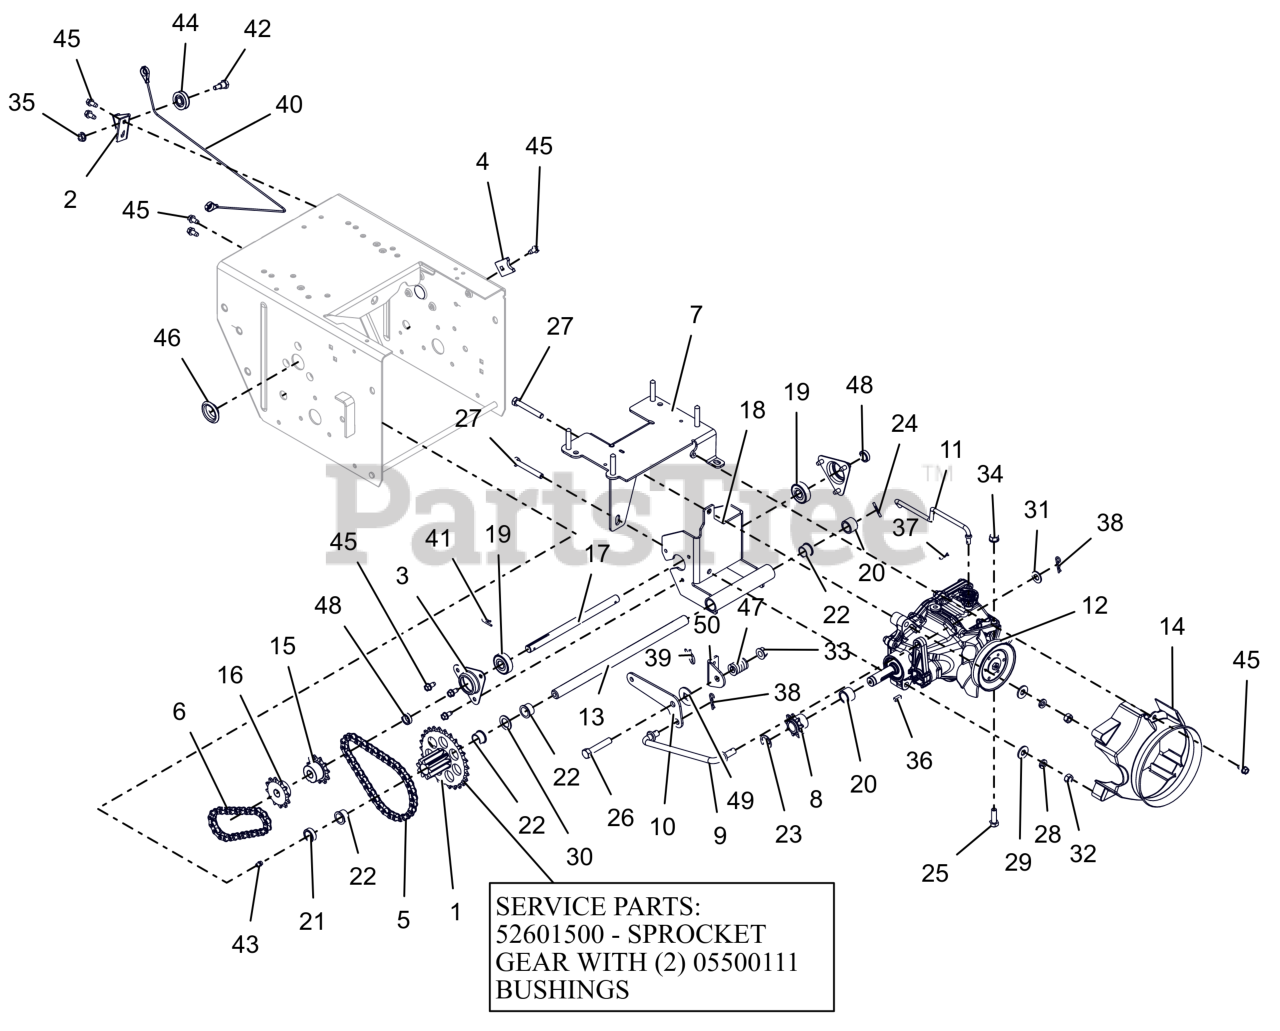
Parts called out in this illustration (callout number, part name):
1	PINION & SPROCKET
1	PINION & SPROCKET W/BUSHINGS
2	BRACKET, CABLE PULLEY
3	FLANGE, BEARING
4	TAB, ANTI ROTATION
5	ROLLER CHAIN #41 - 34 PITCHES
6	CHAIN-ROLLER #41X26 PITCHES
7	BRACKET, HYDROSTATIC TRANS XLG
8	SPROCKET, PINION 9T W/KEY
9	ROD, HYDRO TRANS SHIFT
10	PIVOT, HYDRO TRANS SHIFT
11	ROD, HYDRO BYPASS
12	TRANSMISSION, HYDROSTATIC
13	SHAFT, PINION - HARDENED
14	SHROUD, HYDROGEAR RT-310
15	SPROCKET, 11 TOOTH
16	SPROCKET, 12 TOOTH
17	SHAFT, REDUCTION HEAT TREATED
18	SUPPORT, REDUCTION-BWT
19	BRG-BALL .500X1.38X.437
20	SPACER, .635X.880X.611
21	BSHG-SLV, .635X.880X.305
22	BSHG-FLG .625X.750X.500X.875
23	RG-RTNG-EXT .625X.042
24	@PIN-GRV .125X1.00 TP E ALLOY
25	BLT,HEX .31-18X1.00 G5 ZCC
26	BLT,HEX .38-16X2.00 G5 ZCC
27	BLT, HEX .31-18X2.25 G5 ZCC
28	WSHR, LK-HVY .312X.097 ZCC
29	WSHR,FLT .375X.875X.083 ZCC
30	WSHR, FLT .630X1.005X.062 ZCC
31	WSHR,FLT .406X.812X.065 ZCC
32	NUT, HEX .312-18 ZCC
33	NUT-LK-TOP-FLG .38-16 ZC120
34	NUT-LK-TOP-FLG .312-18 GF ZCC
35	NUT-LK-TOP-FLG .250-20 GF ZCC
36	KEY-SQ .187 X .50 X .187
37	PIN, HAIR #178 .06X.77 ZCC
38	PIN, HAIR #213 .08X1.19 ZCC
39	PIN, SPRING CLIP
40	CABLE, TRACTION, HYDRO PRO
41	CLIP, SPRING
42	BOLT, SHLDR -.375 X .375 X .25-20
43	ZERK,FITTING .25X.125 DRIVE IN
44	PULLEY, CABLE
45	SCR-TAP .25-20X.50 HWH ZCC
46	PLUG, HOLE - 1.125"
47	SG-COMP .187X.56X1.62
48	SPCR, SLV
49	FRICTION WASHER
50	BRACKET, HYDRO SHIFT PIVOT
